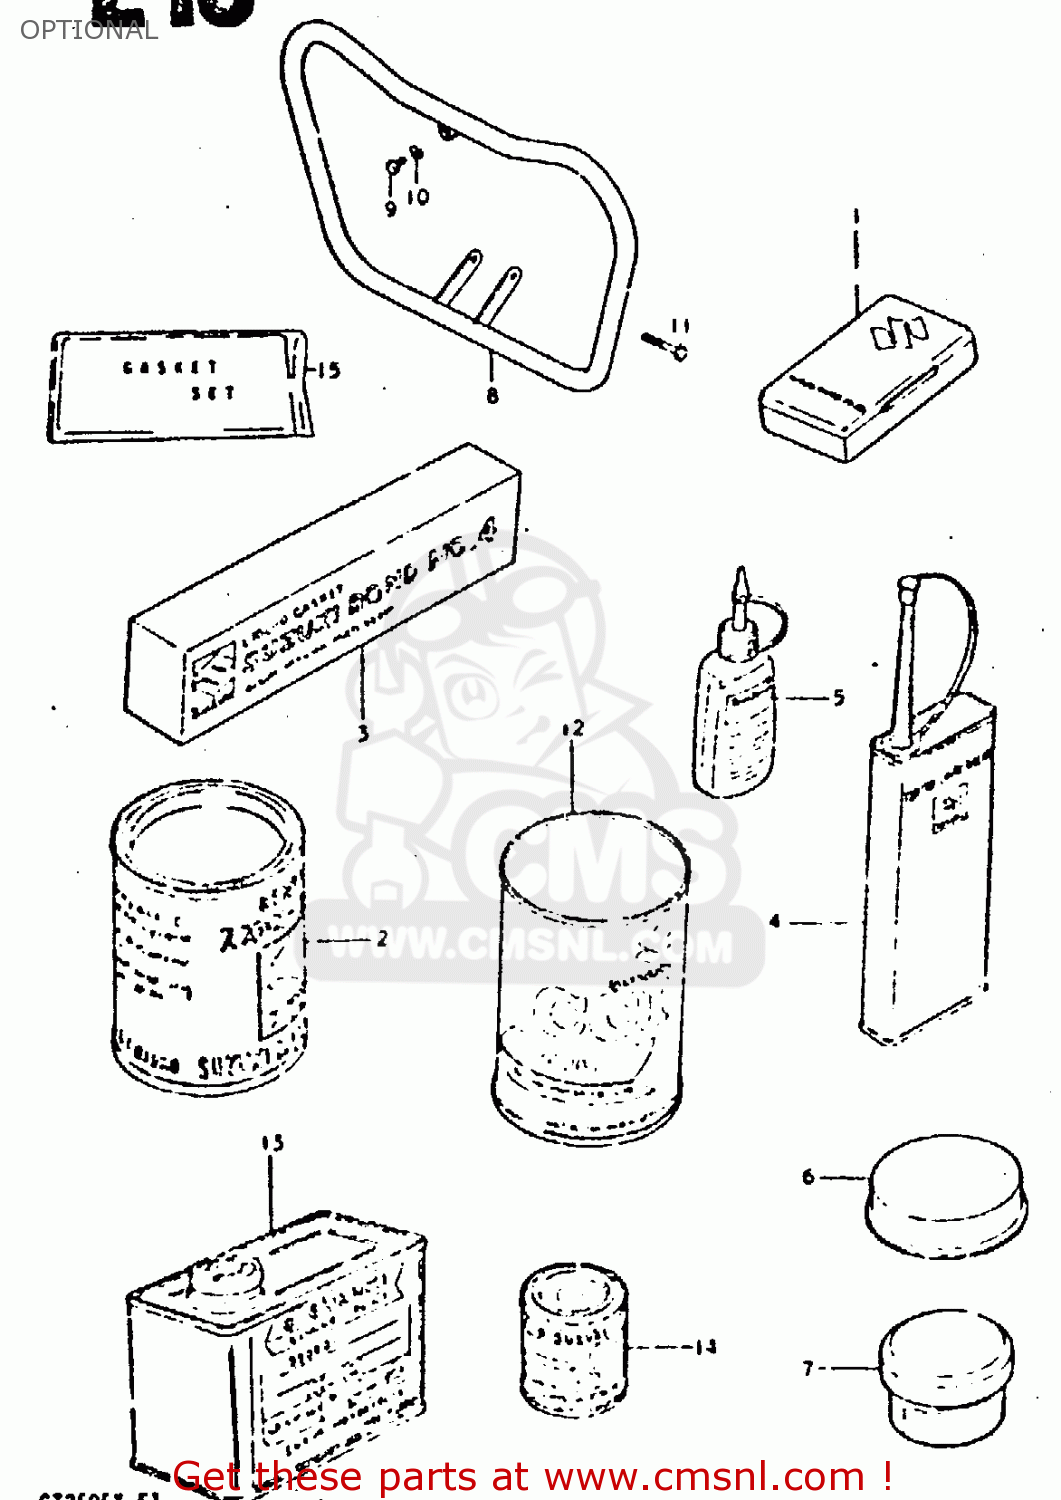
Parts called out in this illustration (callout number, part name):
1	TUBE REPARING TOOL
2	GREASE(C)EP2 LITHIUM 150G
3	BOND 1104
4	THREAD LOCK NO.1401 CLEAR 200G
5	THREAD LOCK NO.1342
6	GREASE,SILICON 20G
7	GREASE,PBC FOR BRK PAD 20G
8	BUMPER, FRONT
9	BOLT 10X20
10	LOCK WASHER
11	BOLT
12	CCI OIL 1LX24
13	PAINT (BLACK)
14	PAINT,BLACK
15	GASKET SET,ENG (MCA)
